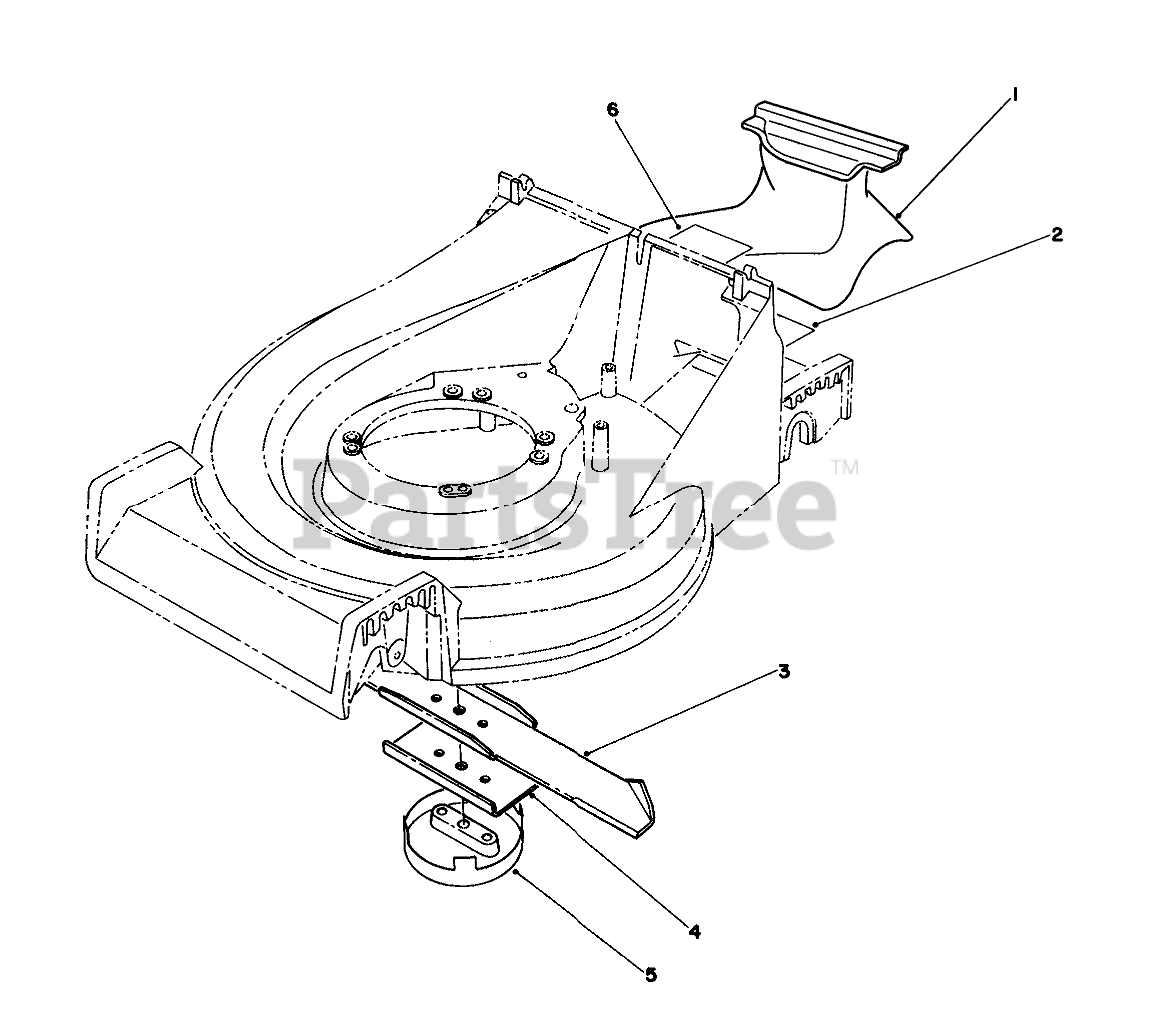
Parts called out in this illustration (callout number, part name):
1	RECYCLER PLUG
2	DECAL - MULCHER KIT
3	BLADE-21in
4	Stiffener
5	CUP-SCALP, ANTI
6	DECAL - FRENCH
